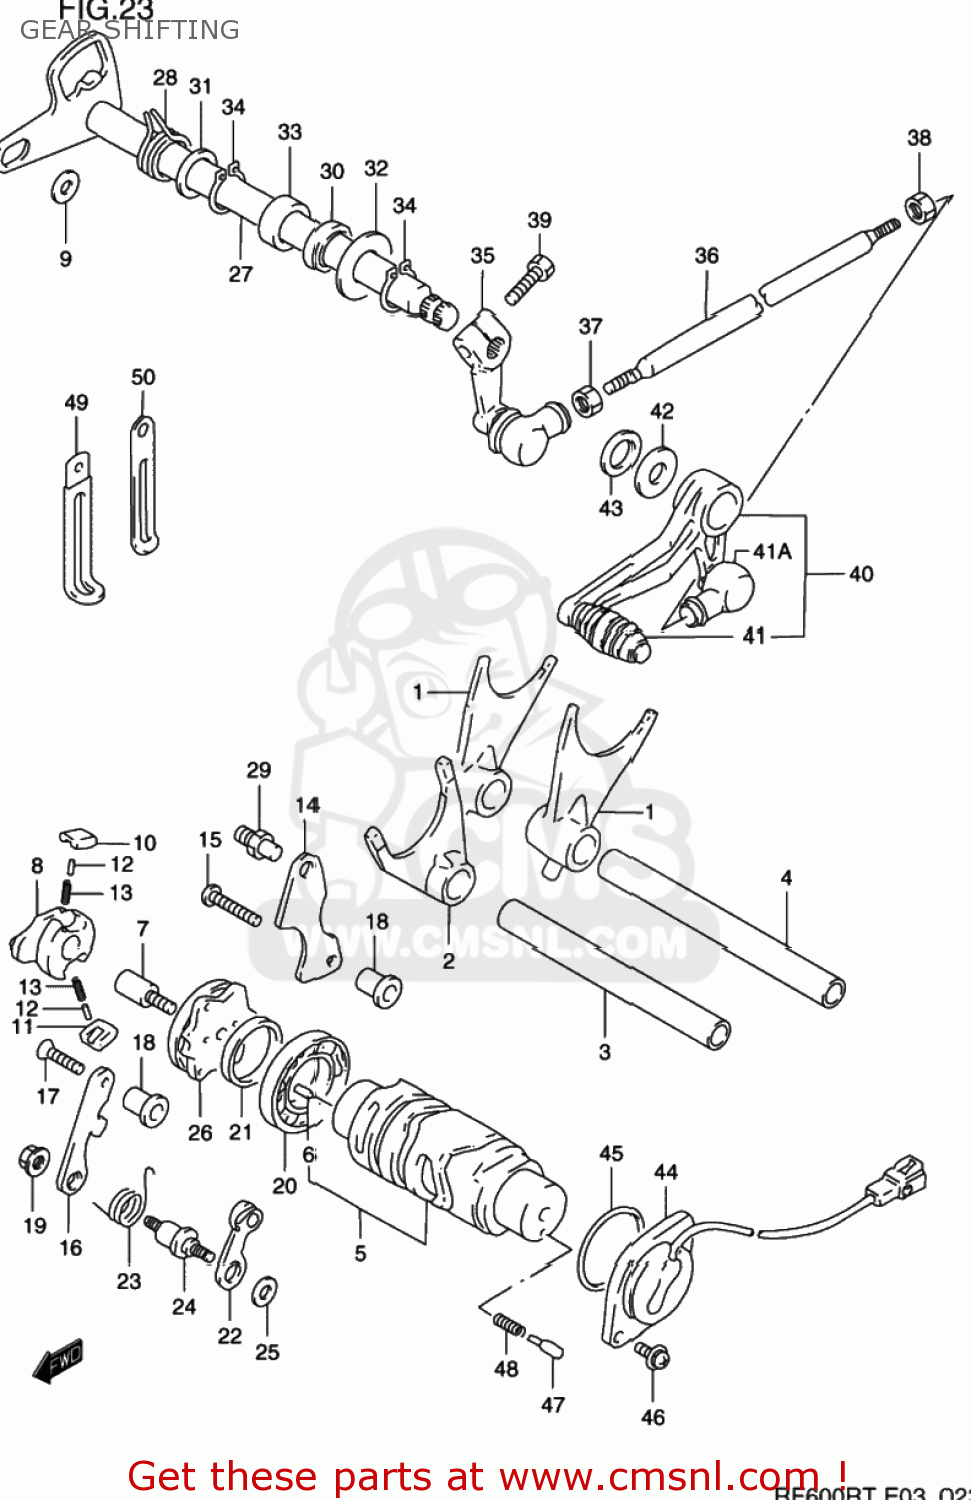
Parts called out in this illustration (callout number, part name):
1	FORK,GEAR SHIFT NO.1
2	FORK,GEAR SHIFT NO.3
3	SHAFT,GEAR SHIFT FORK
4	SHAFT,GEAR SHIFT FORK(L:128)
5	CAM,GEAR SHIFT
6	PIN
7	PIN,SHIFT CAM DRIVEN GEAR
8	SHIFTER,GEAR SHIFT CAM
9	SPACER(7X10X5)
10	PAWL,GEAR SHIFT NO.1
11	PAWL,GEAR SHIFT NO.2
12	PIN(5X8)
13	SPRING
14	LIFTER,GEAR SHIFT PAWL
15	SCREW 6X30
16	GUIDE,GEAR SHIFT CAM
17	SCREW
18	SPACER(6.1X10X16)
19	NUT
20	BEARING(25X47X8)
21	WASHER(25X32X3)
22	STOPPER,GEAR SHIFT CAM
23	SPRING,STOPPER ARM
24	SUPPORT,CAM STOPPER ARM
25	WASHER
26	PLATE,GEAR SHIFT CAM
27	SHAFT,GEAR SHIFT
28	SPRING
29	STOPPER,GEAR SHIFT CAM
30	SEAL,OIL(14X22X6)
31	WASHER,THRUST
32	WASHER(14X29X0.8)
33	BEARING(14X20X12)
34	CIRCLIP
35	ARM,GEAR SHIFT LINK
36	ROD,GEAR SHIFT LINK
37	NUT
38	NUT
39	BOLT
40	LEVER ASSEMBLY,GEAR SHIFTING
41	RUBBER,GEAR SHIFT PEDAL
41A	COVER,DUST
42	WASHER(14X27X4)
43	WASHER(18X24X1)
44	TERMINAL BASE ASSY,NEUTRAL
45	O RING(D:2.4,ID:35.5)
46	SCREW
47	PIN(5X15.5)
48	SPRING
49	CLAMP
50	CLAMP
